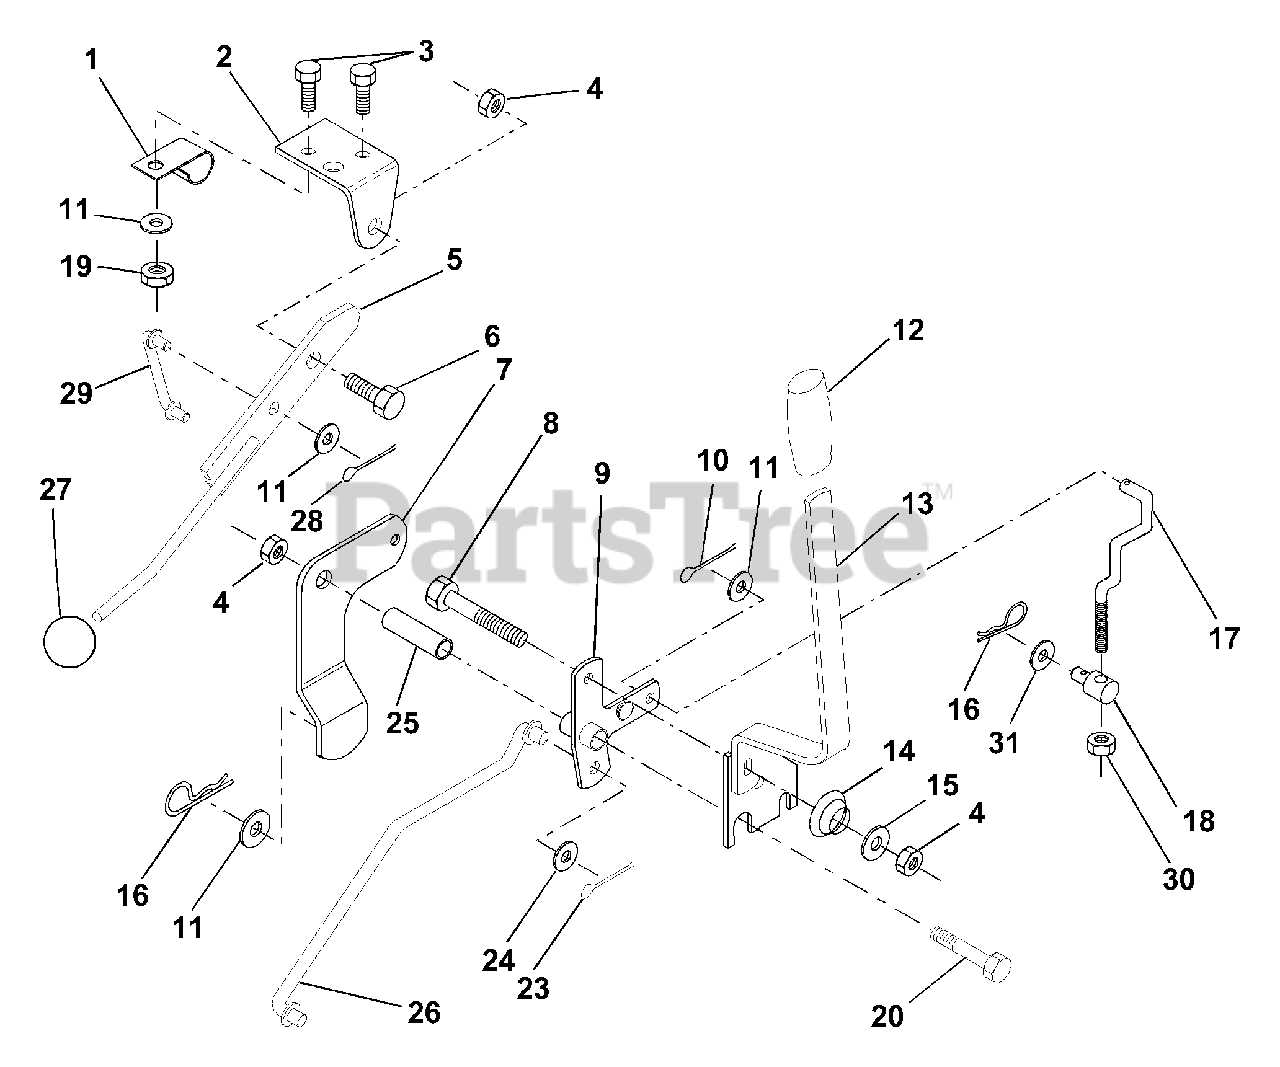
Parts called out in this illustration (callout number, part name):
1	Clip, Insulated
2	Bracket, Mower Clutch
3	Bolt, Fin. Hex 1/4-20 UNC x 1/2
4	Nut, Crownlock 3/8-16
5	Assembly, Clutch Lever
6	Bolt, Shoulder
7	Assembly, Mower Clutch Arm
8	Bolt, Hex 3/8-16 UNC x 2-1/4
9	Assembly, Bellcrank Lift
10	Pin, Cotter 1/8 x 3/4
11	Washer 13/32 x 13/16 x 16 Ga.
12	Grip, Handle
13	Assembly, Lift Handle
14	Spring, Compression
15	Washer 13/32 x 3/4 x 12 Ga.
16	Retainer, Spring
17	Link, Front Lift
18	Trunnion, Threaded 3/8-16
19	Nut, Crownlock 1/4-20
20	Bolt, Fin. Hex 3/8-16 UNC x 2-3/4
23	Pin, Cotter 1/8 x 1
24	Washer 17/32 x 1 x 12 Ga.
25	Tube, Spacer
26	Rod, Mower Lift
28	Pin, Cotter 3/32 x 3/4
29	Link, Mower Clutch
30	Nut Hex Jam 3/8-16 x 1.30
31	Washer 13/32 x 1-1/4 x 12 Ga.
